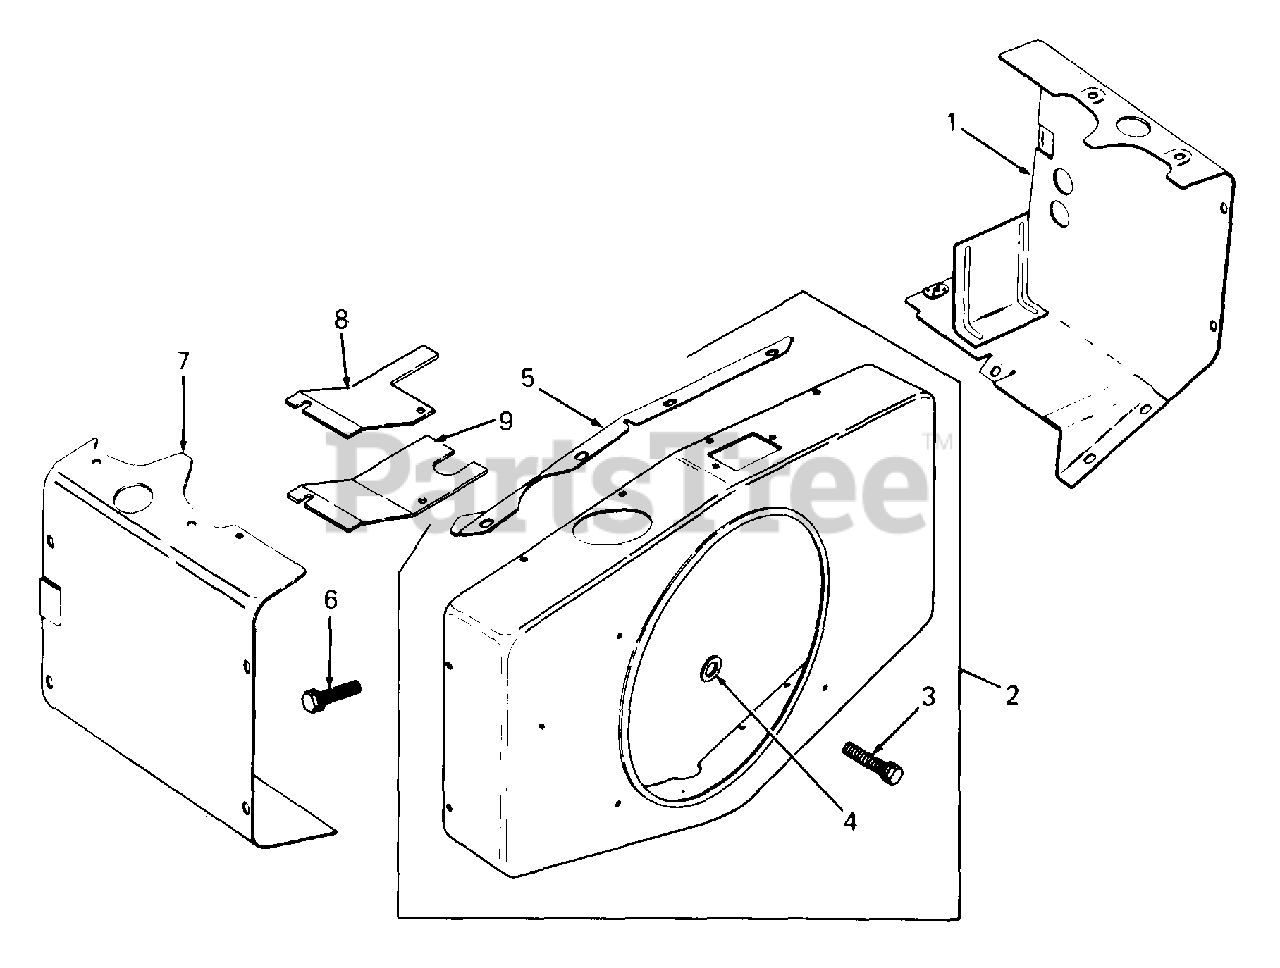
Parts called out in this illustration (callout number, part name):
1	Baffle, #1 Cylinder Head
2	Kit, Blower Housing
3	Screw, Self Tap, 1/4-20 x .62 Lg
4	Washer, Flat, 1/4
5	Support, Upper Housing
6	Screw, Hex Wash Hd, 1/4-20 x .43 Lg
7	Baffle, #2 Cylinder Head
8	Baffle, #2 Cylinder Top
9	Baffle, Pump
